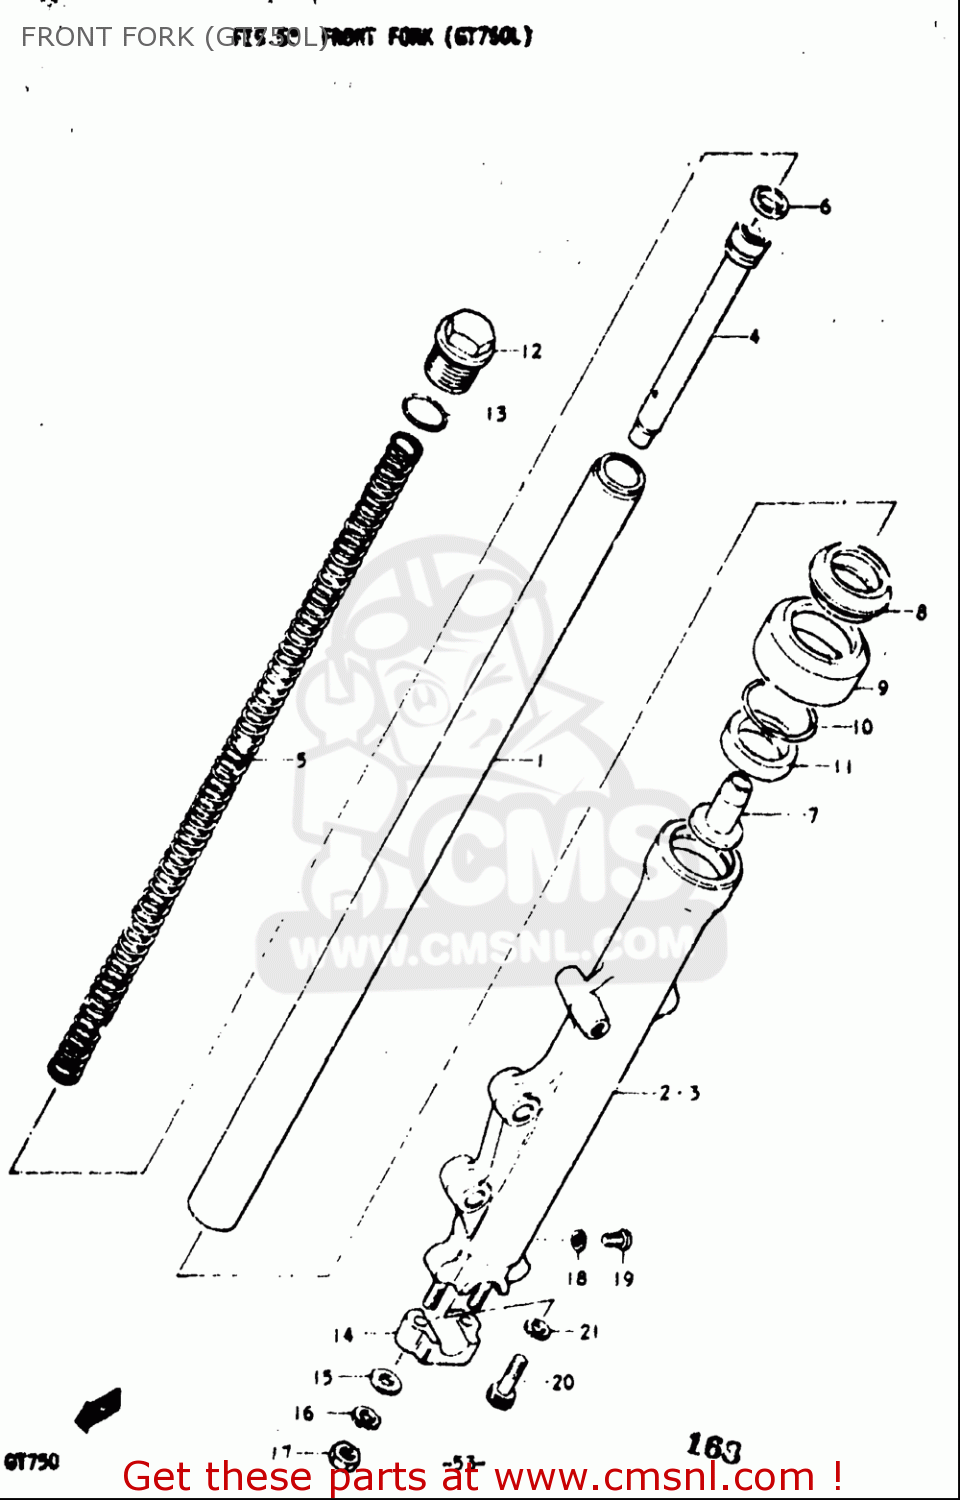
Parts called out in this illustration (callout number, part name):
6	RING
7	PIECE,OIL LOCK
8	DUST SEAL,FR FORK
11	SEAL,OIL 35X48X11
12	CAP,INNER TUBE
13	O RING
14	HOLDER,AXLE
15	WASHER
16	WASHER,LOCK
17	NUT
18	GASKET (NAS)
19	SCREW 4X6
20	BOLT(8X27)
21	GASKET (NAS)
